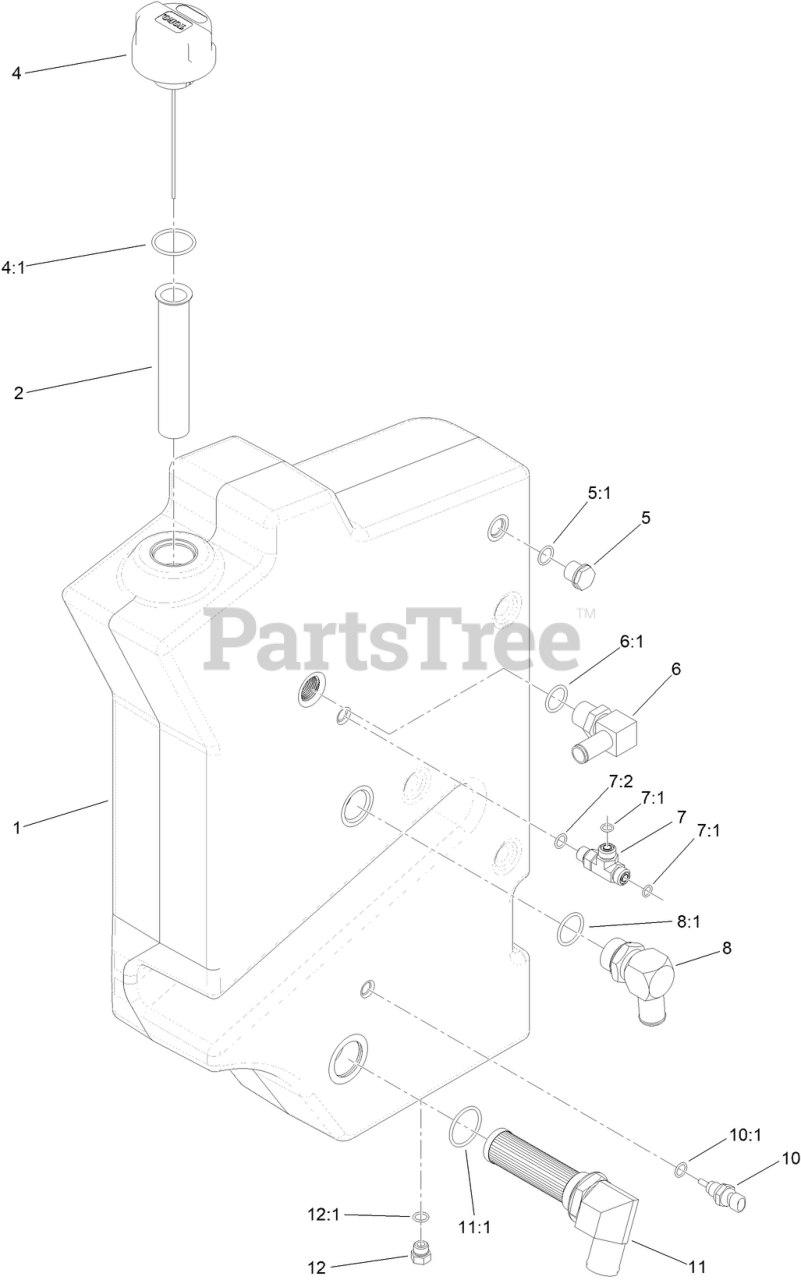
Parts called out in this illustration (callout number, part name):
1	TANK ASM-HYD
2	FILTER-SCREEN
4	CAP-HYDRAULIC, VENTED BREATHER
4:1	O-RING
5	SIGHT GLASS ASM
5:1	O-RING
6	FITTING-ELBOW, 90
6:1	O-RING
7	FITTING-TEE
7:1	O-RING
7:2	O-RING
8	STEM-BARB-90
8:1	O-RING
10	SENDER-TEMPERATURE
10:1	O-RING
11	STRAINER FITTING ASM
11:1	O-RING
12	PLUG-HH
12:1	O-RING
